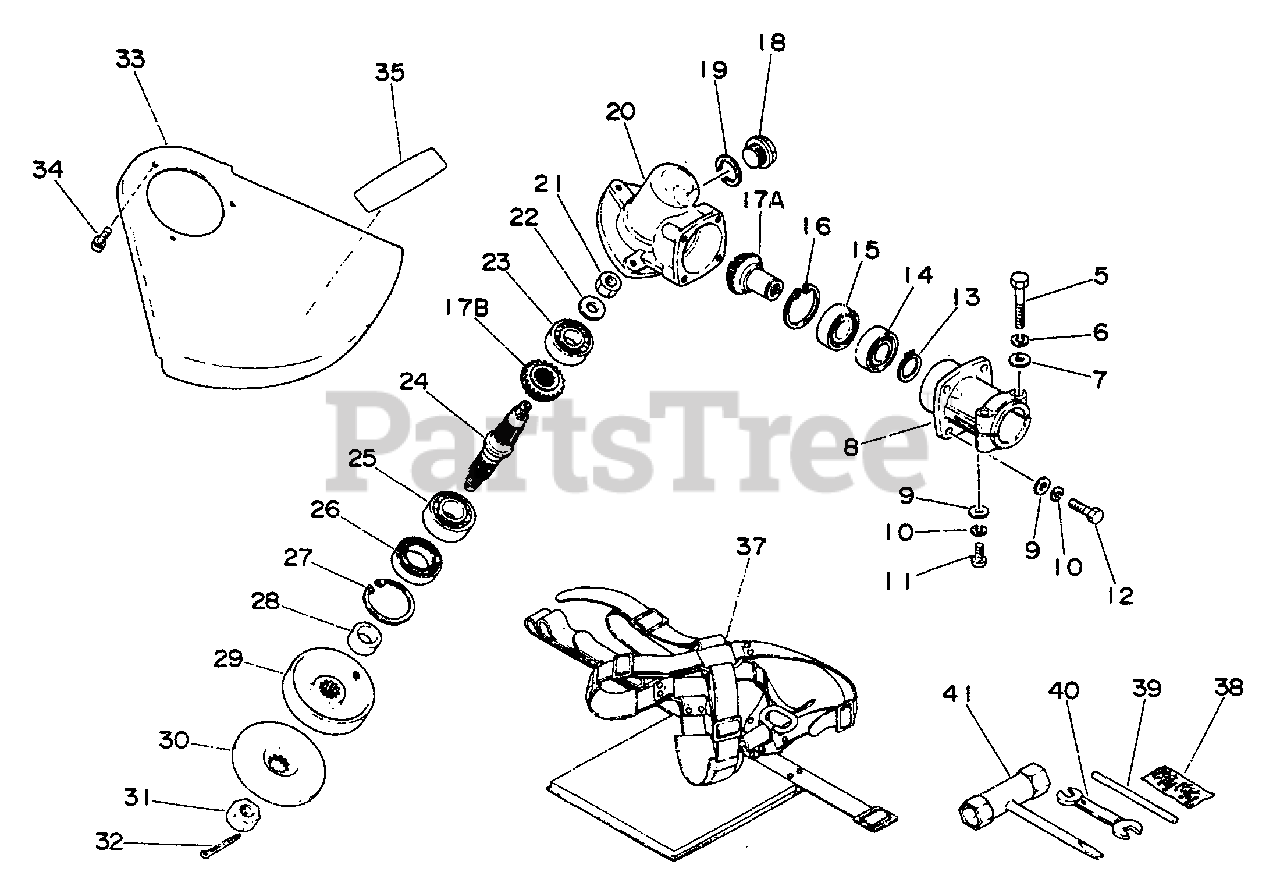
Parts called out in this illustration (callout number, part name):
5	BOLT - 6X32
6	LOCKWASHER - 6
7	WASHER - 6
8	CASE, GEAR
9	WASHER - 5
10	LOCKWASHER - 5
11	SCREW - 5X12
12	BOLT - 5X20
13	RING, RETAINING - 15
14	BEARING, BALL - 6002D
15	BEARING, BALL - 6002
16	RING, RETAINING - 32
18	FITTING, GREASE
19	CASE, GEAR
20	CASE, GEAR
22	WASHER - 8
23	BEARING, BALL - 6201
24	GEAR - SHAFT
25	BEARING, BALL - 6202
26	SEAL, OIL
27	RING, RETAINING - 35
29	ADAPTOR, BLADE - UPPER
30	ADAPTOR, BLADE - LOWER
31	NUT - 10 -- LEFT HAND
32	PIN, SPLIT - 2X22
33	SHIELD, DEBRIS
34	SCREW - 5X14
35	LABEL - ECHO
37	SHOULDER STRAP ASSY
38	PIN, SPLIT - 2X22
39	LOCKING TOOL
40	SPANNER - 8X10mm
41	T-WRENCH
